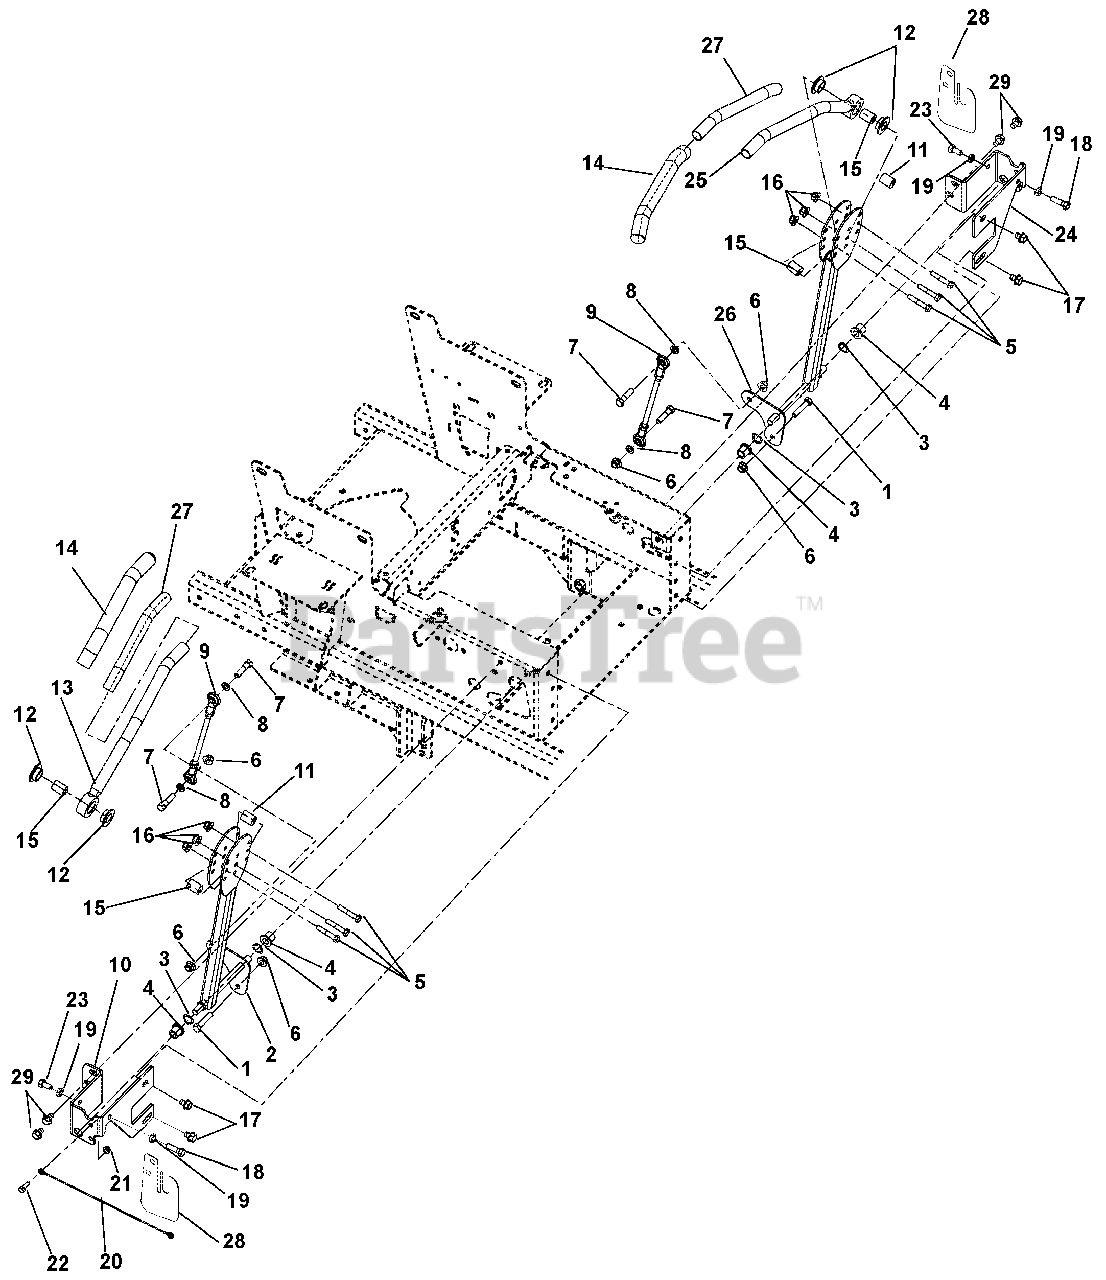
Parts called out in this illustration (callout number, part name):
1	Bolt, Hex .38-16 x 2.00 Full Thread
2	Weldment, Right Hand Control
3	Wave Washer .640 x .875 x .125 Free Height
4	Bushing, Flange .515 x .750 x .745 x 1.00 Nylon
5	Bolt, Hex .31-18 x 1.75
6	Nut, .38-16 Nyloc Flange
7	Bolt, Hex .38-16 x 1.50
8	Washer, Locking .38 x .094 Regular
9	Assembly, Steering Linkage
10	Bracket, Right Hand Steering Stop
11	Eccentric
12	Bushing, Flange .762 x 1.48 x .44 Nylon
13	Weldment, Handle Right Hand
14	Grip, Handlebar
15	Spacer, .328 x .76 x 1.01
16	Nut, .31-18 Nyloc Flange
17	Screw, Tapping .38-16 x .50 Hex Washer Head Thread Rolling
18	Bolt, Hex .38-16 x 1.25
19	Nut, Hex-Jam .375-16
20	Cable, 12.0 Lanyard, Nylon
21	Nut, .25-20 Nyloc Flange
22	Bolt, Hex .25-20 x .75
23	Bolt, Hex .38-16 x .75
24	Bracket, Left Hand Steering Stop
25	Weldment, Handle Left Hand
26	Weldment, Left Hand Control
28	Plate, Side Cover
29	Screw, Tapping .38-16 x .75 Hex Washer Head Thread Rolling
